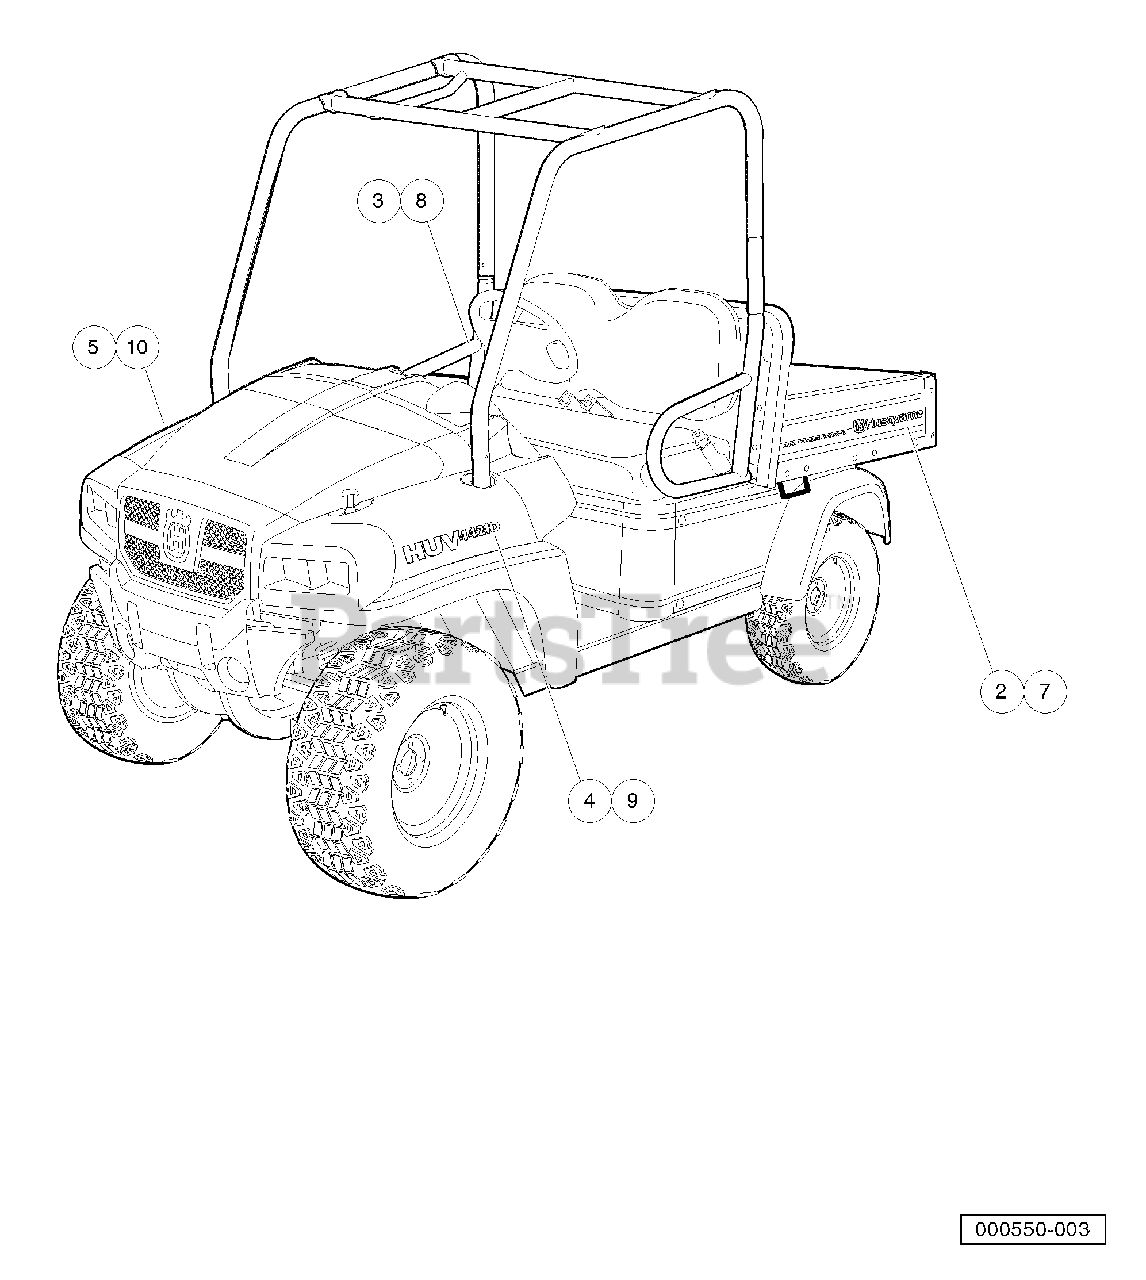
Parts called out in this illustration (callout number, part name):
2	Decal, Bed, Huv, Orange, Ds
3	Decal, Bed, Huv, Orange, Ps
4	Decal, Huv 4421d, Orange, Ds
5	Decal, Huv 4421d, Orange, Ps
6	Instl,decal,huv4421d,olv Grn
7	Decal, Bed, Huv, Olv Grn, Ds
8	Decal, Bed, Huv, Olv Grn, Ps
9	Decal, Huv 4421d, Olv Grn, Ds
10	Decal, Huv 4421d, Olv Grn, Ps
